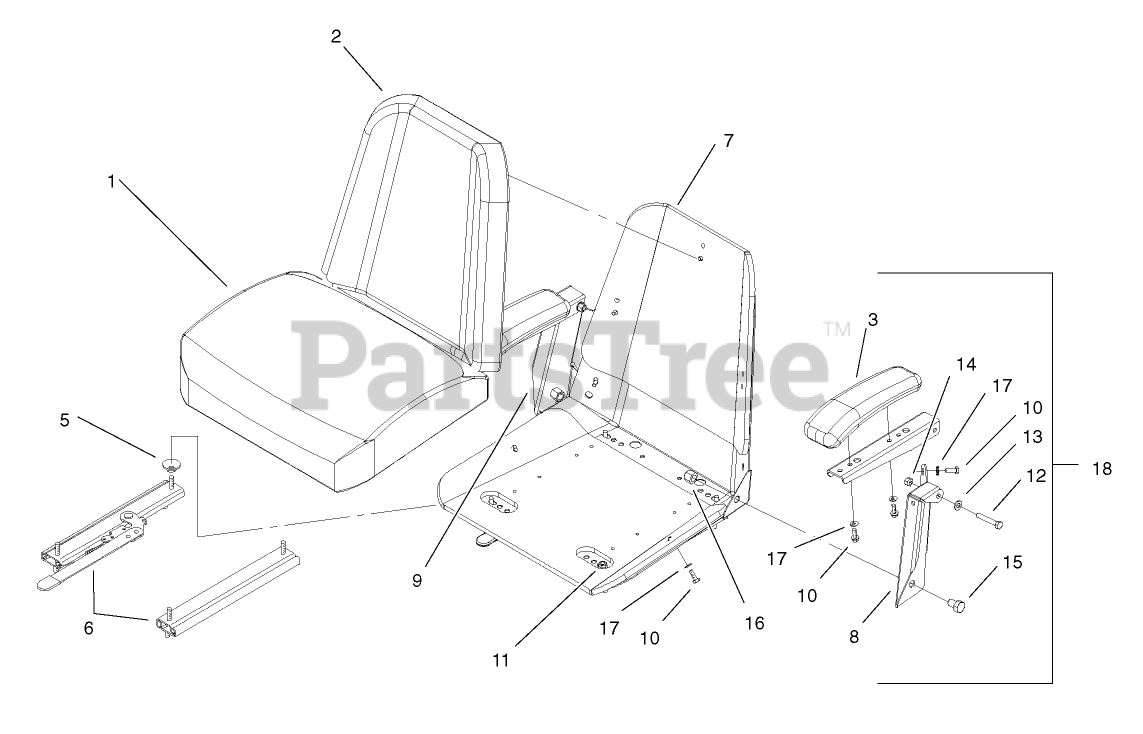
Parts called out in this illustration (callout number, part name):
1	CUSHION-SEAT, BOTTOM
2	CUSHION-SEAT, BACK
3	CUSHION-ARMREST
5	SPACER-TRACK
6	TRACK-SEAT
7	FRAME-SEAT
8	Bracket-Armrest, LH
9	Bracket-Armrest, RH
10	SCREW-HH
11	NUT-HF
12	SCREW-HH
13	WASHER-PLAIN
14	NUT-LOCK, NI
15	SCREW-HH
16	NUT-LOCK, NI
17	WASHER-FLAT
18	ARMREST KIT
